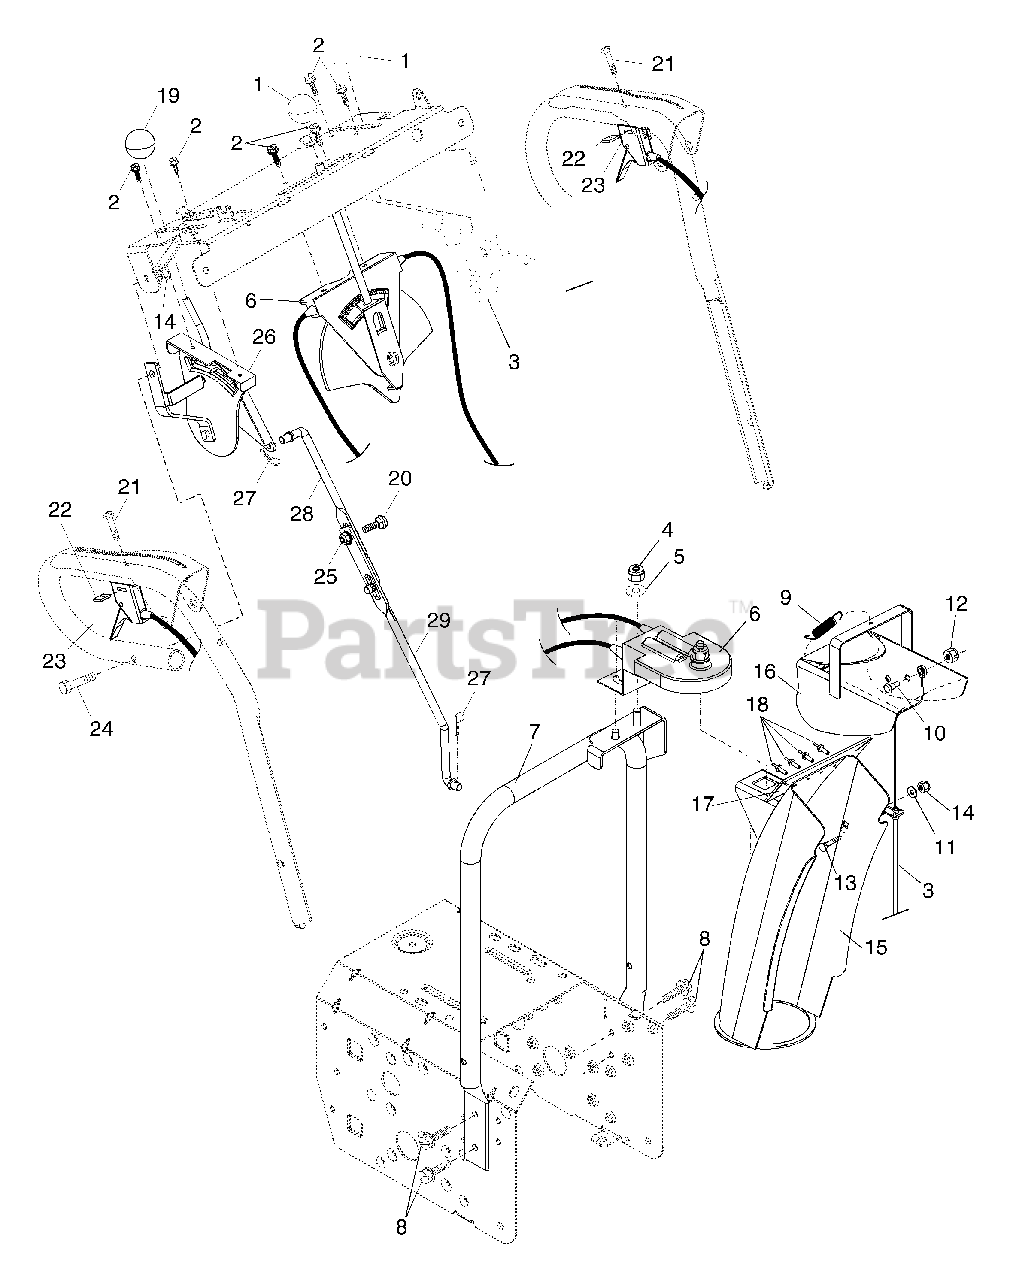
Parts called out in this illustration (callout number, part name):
1	Knob, Lever
2	Screw #10-24 x 5/8
3	Control Assembly, Deflector
4	Nut, Lock 3/8-16
5	Washer, Flat 3/8
6	Control Assembly, Chute Rotater
7	Support, Pivot
8	Screw, Hex Head 5/16-18 x 3/4
9	Spring, Deflector
10	Bolt, Shoulder
11	Washer, Flat
12	Nut, Lock 1/4-20
13	Bolt, Carriage 5/16-18
14	Nut, Lock 5/16-18
15	Chute Assembly
16	Deflector Assembly
17	Seal, Deflector
18	Rivet, Blind
19	Knob, Speed Control Lever
20	Bolt, Carriage 5/16-18 x 3/4
21	Screw #10-24 x 1-1/2
22	Nut, Weld #10-24
23	Control Assembly, Power Steering
24	Screw, Hex Head 5/16-18 x 1-3/4
25	Nut, Lock 5/16-18
26	Lever Assembly, Speed Control
27	Retainer, Hairpin
28	Rod, Upper, Speed Control
29	Rod, Lower, Speed Control
